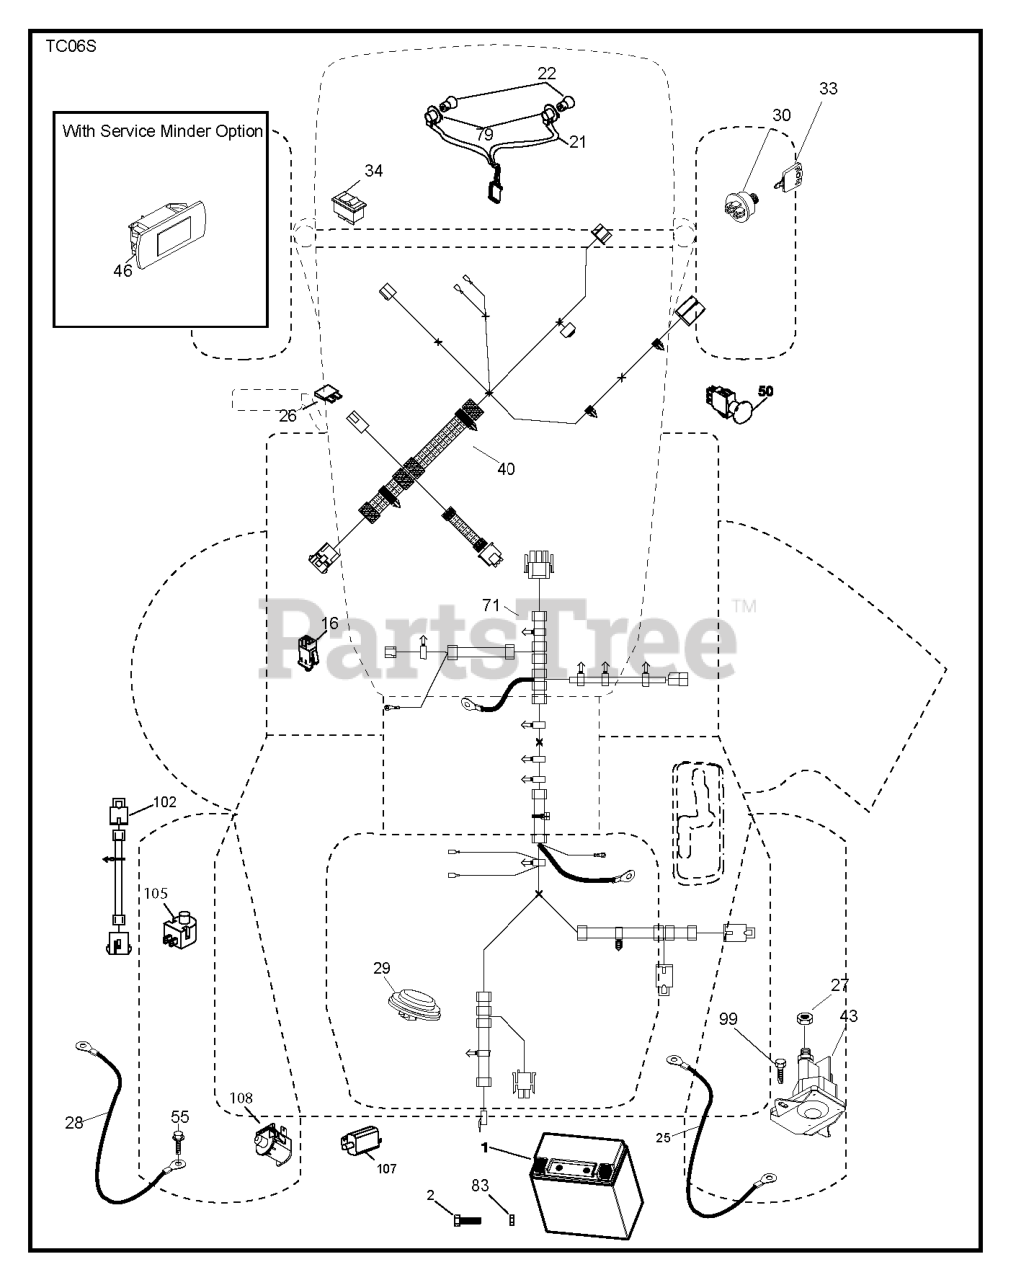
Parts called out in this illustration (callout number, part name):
1	BATTERY BATTERY 14AH 12V LEOC
2	SCREW.HEX.HEAD.CAP.M6 X1.12W
16	SWITCH INTERLOOK PUSH-IN
21	HARNESS.LIGHT W/4152J BULBS
25	CABLE CABLE.RED.20.8AWG.M6.CRD
26	FUSE 20AMP
27	NUT
28	CABLE CABLE.BLACK.20.8AWG.M6.C
29	SWITCH.SEAT.DELTA.OPC.
30	SWITCH.IGN.DELTA.W.LGH.ROS
33	KEY.CHAIN.BLISTER.PACK.GEN.INT
40	WIRING HARNESS
43	SOLENOID.W/BRASS.PLUNGER
46	RP.GUAGE.SRVCMNDR.HRMTR.
50	RP.PTO.SWITCH.8 TERMINAL.BLACK
55	SCREW 5/16"
71	HARNESS
79	BULB HOLDER ASM.
83	NUT NUT SQUARE
99	SCREW
102	HARNESS ASSY
105	REVERSE SWITCH
107	.WITCH.FULL BAGGER.INDICATOR
108	SWITCH.SNAPMOUNT.NC
